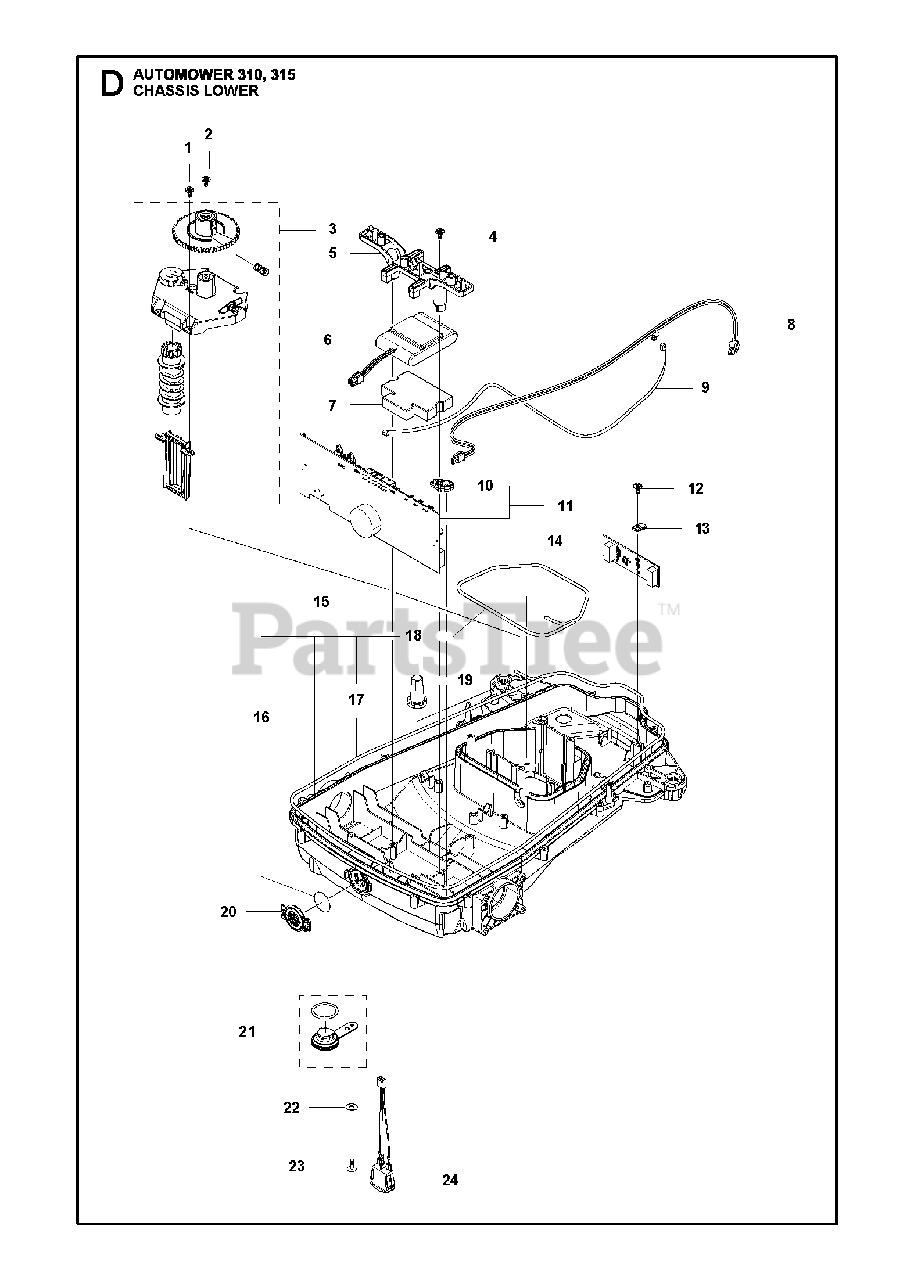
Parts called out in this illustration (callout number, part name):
1	SCREW ITXPANT
2	SCREW ITXPANT
3	Cover Kit
4	SCREW ITXPANT
5	HOLDER BATTERY
6	BATTERY
7	WEIGHT CENTER
8	LOOM CHARGING LINK
9	LOOM LOOP SENSOR
10	CLIP PCB
11	PCB MAIN BOARD
12	SCREW ITXPANT
13	CLAMP PCB
14	PRINTED CIRCUIT ASSY LOOP SENS
15	CHASSIS KIT LOWER
16	KIT AIR FILTER KIT 305 - 10 PC
17	SEALING STRIP P 15 CHASSI LOW
18	SEALING STRIP P15 UPPER
19	COLUMN FRONT
20	COVER AIR FILTER
21	PLUG KIT
22	WASHER
23	SCREW ITXPANT
24	LOOM ON/ OFF
